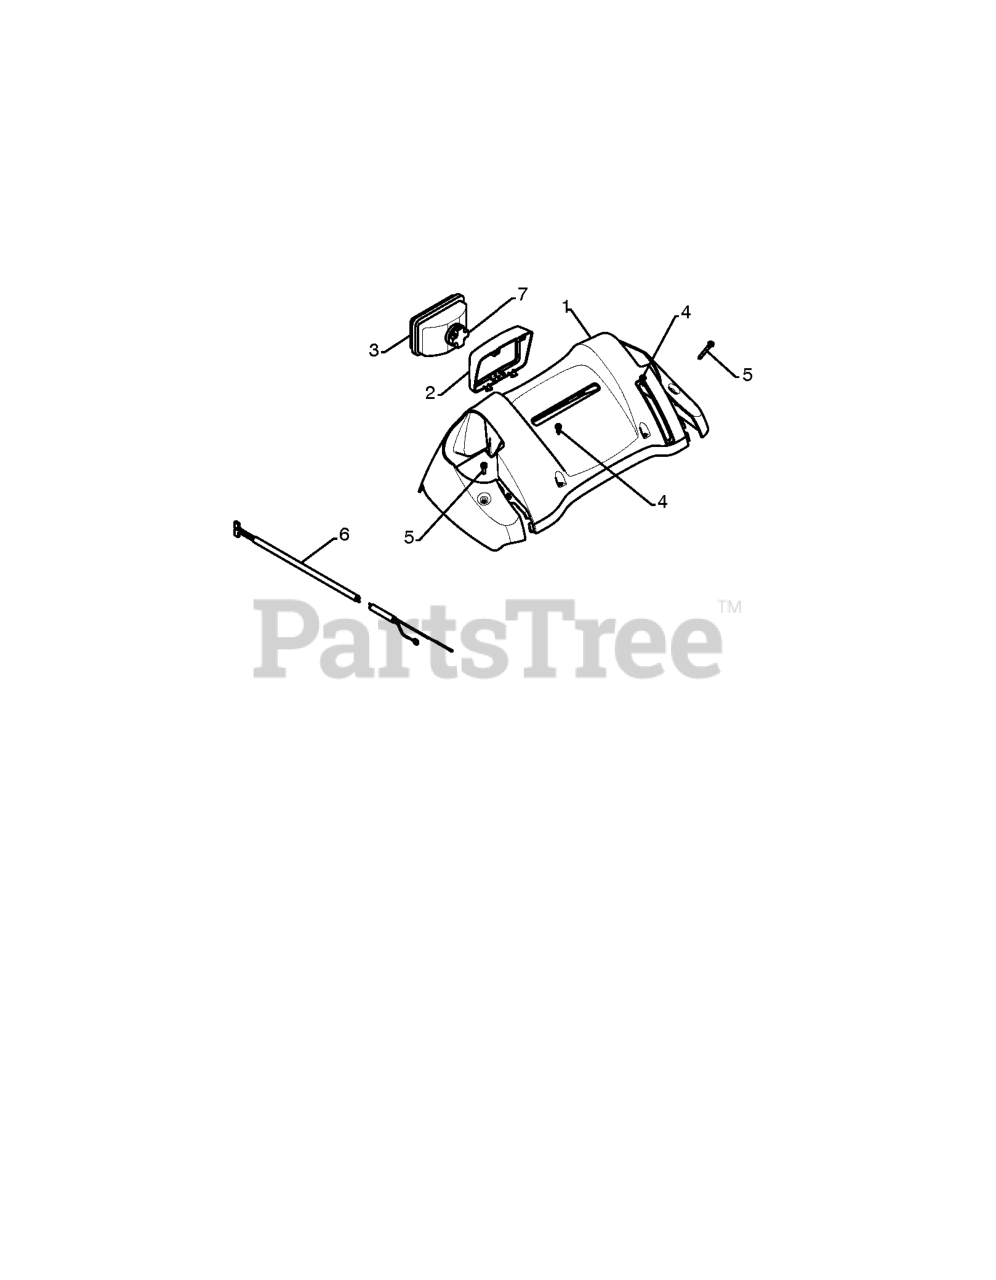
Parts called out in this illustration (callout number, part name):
1	PANEL.CONSOLE.FLOOD.LIGHT.GREY
2	BEZEL.HEADLIGHT
3	RP.HEADLIGHT.FLOOD.SNOW
4	SCREW, HEX HEAD, TAPPING
5	SCREW, HEX HD TAPPING #10-24 1
6	HARNESS, HEADLIGHT (FLOOD)
7	BULB.HEADLIGHT.FLOOD.1156-12V
